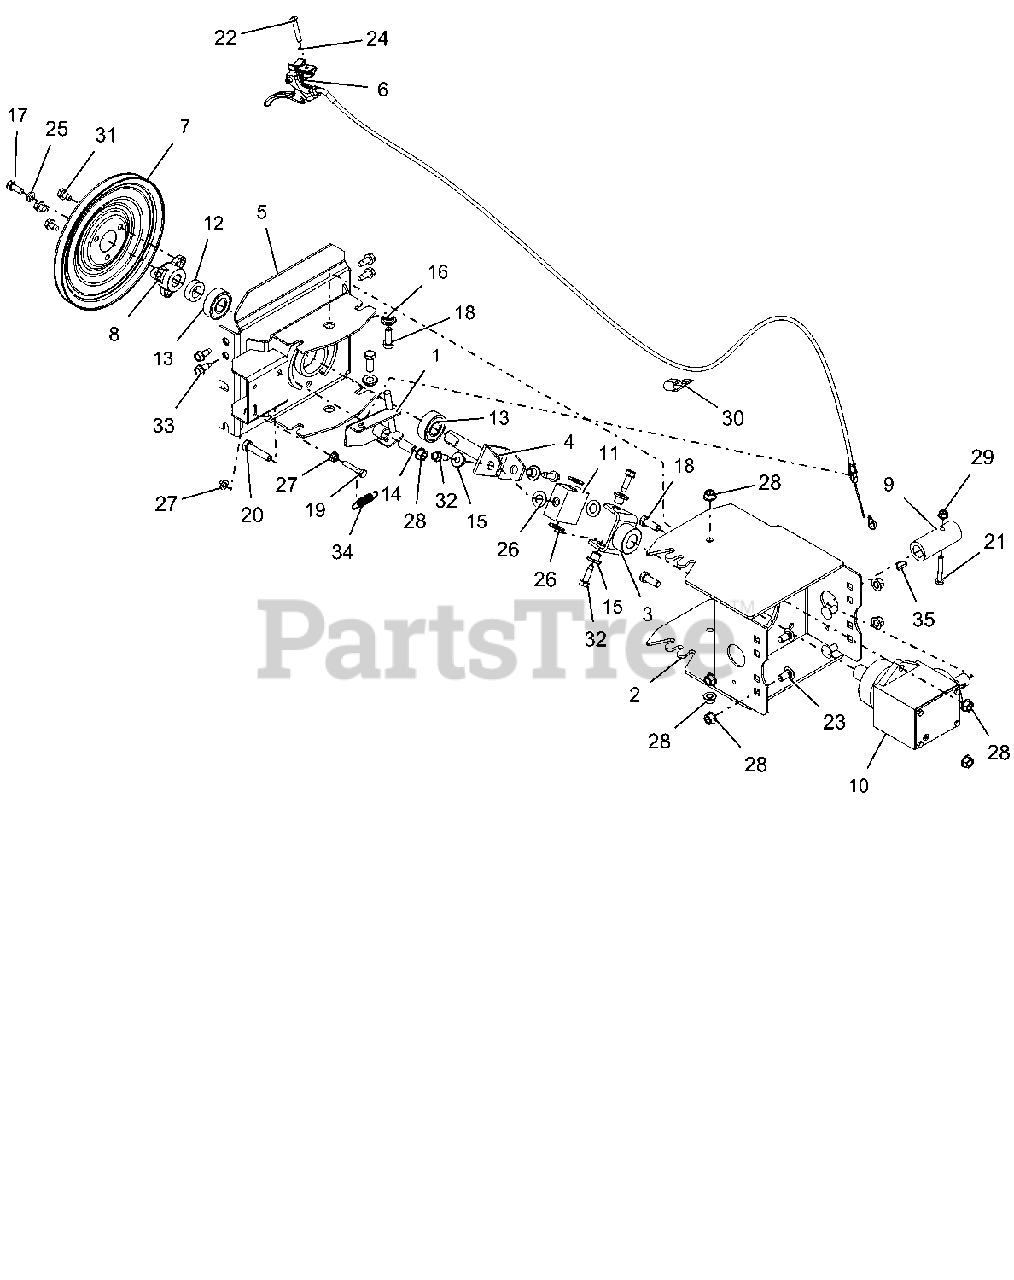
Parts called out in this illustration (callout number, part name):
1	ARM, PIVOT LOCK (BLACK)
2	ADAPTOR, BRUSH FRAME (BLACK)
3	JOINT,UNIVERSAL (BLACK)
4	JOINT, UNIVERSAL (BLACK)
5	ADAPTOR, FRAME -20000 SERIES (BLACK)
6	CABLE, REMOTE BRUSH LOCK
7	PULLEY, SPIN FORM SINGLE GROOVE
8	HUB, ATTACHMENT PULLEY
9	HUB, COUPLING
10	GEARBOX, 1:1 CCW-CW W/CRSBOR
11	BLOCK, UNV
12	SPACER, .755x1.250x.370
13	BRG-BALL .750X1.781X.61
14	BSHG, SLV .385 X .500 X 1.045
15	BSHG, FLG .325X.500X.513X.875
16	BSHG, FLG .406X.88X.270X.140
17	BLT-HEX .31-24X.75 GR5 YWZC
18	BLT-HEX .38-16X1.00 GR5 YWZC
19	BLT-HEX .25-20X1.50 GR5 YWZC
20	BLT-HEX .38-16X1.75 GR5 YWZC
21	BLT-HEX .25-20X1.75 GR5 YWZC
22	SCR, -- MCH .25-20X1.50 OVAL HD
23	BLT-RDHDSQNK .38-16X.75 G5 YWZC
24	WSHR, LK-INT .250 TH TYA
25	WSHR-LK .31X.097 HVY YWZC
26	WSHR-HDND .515X.970X.062
27	@NUT-SPNLK-FLG .25-20 YWZC
28	NUT, LK-TOP-FLG .38-16 YWZC
29	NUT, LK-TOP-FLG .25-20 YWZC
30	CLAMP, J
31	SCR-TAP .31-18X.50 HWH TR YWZ
32	SCR-TAP .31-18X1.00 HWH TR YZ
33	SCR-TAP .31-18X.75 HWH TR YWZ
34	SPRG, EXTENSION
35	KEY, WDRF - .188X.75X.313 REV
